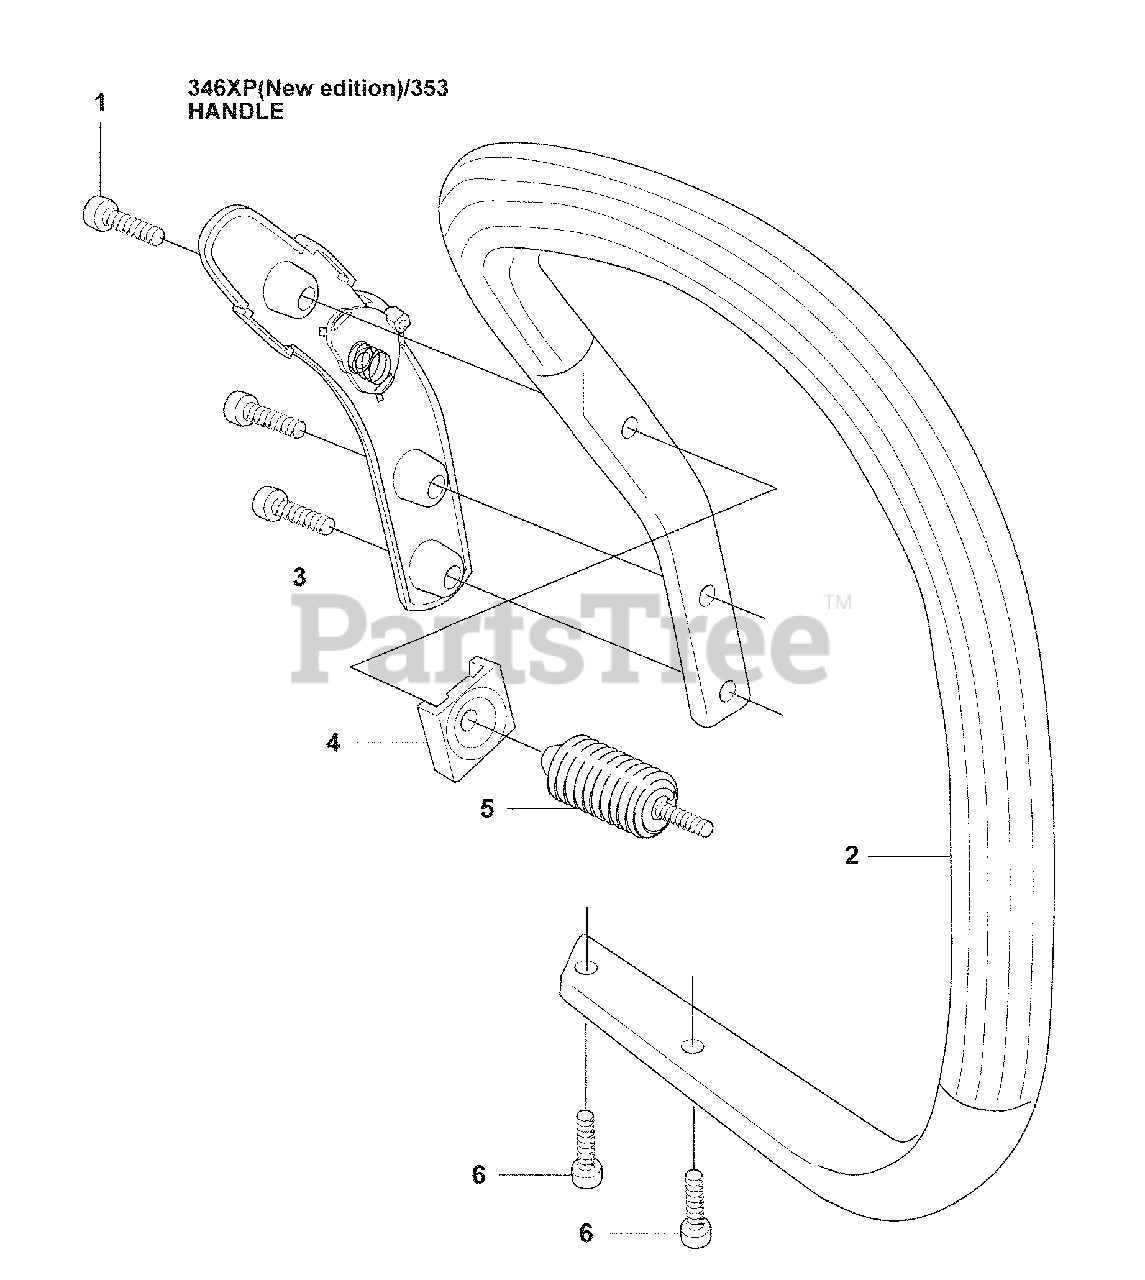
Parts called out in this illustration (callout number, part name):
1	Screw, 3 X 25 IHSCFT
2	Front Handle
6	Screw, Ihscft
